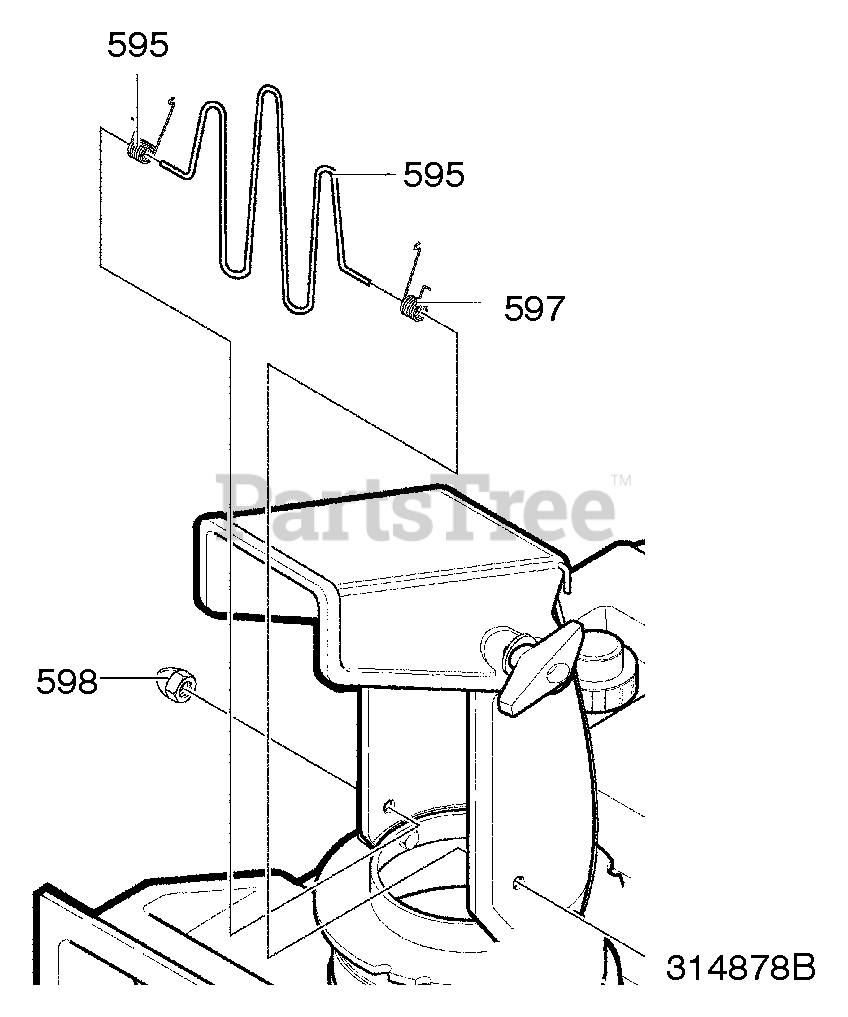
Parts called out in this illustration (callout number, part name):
595	GUARD, WIRE CHUTE
596	SPRING, TORSION
597	SPRING, TORSION
598	NUT, ACORN
